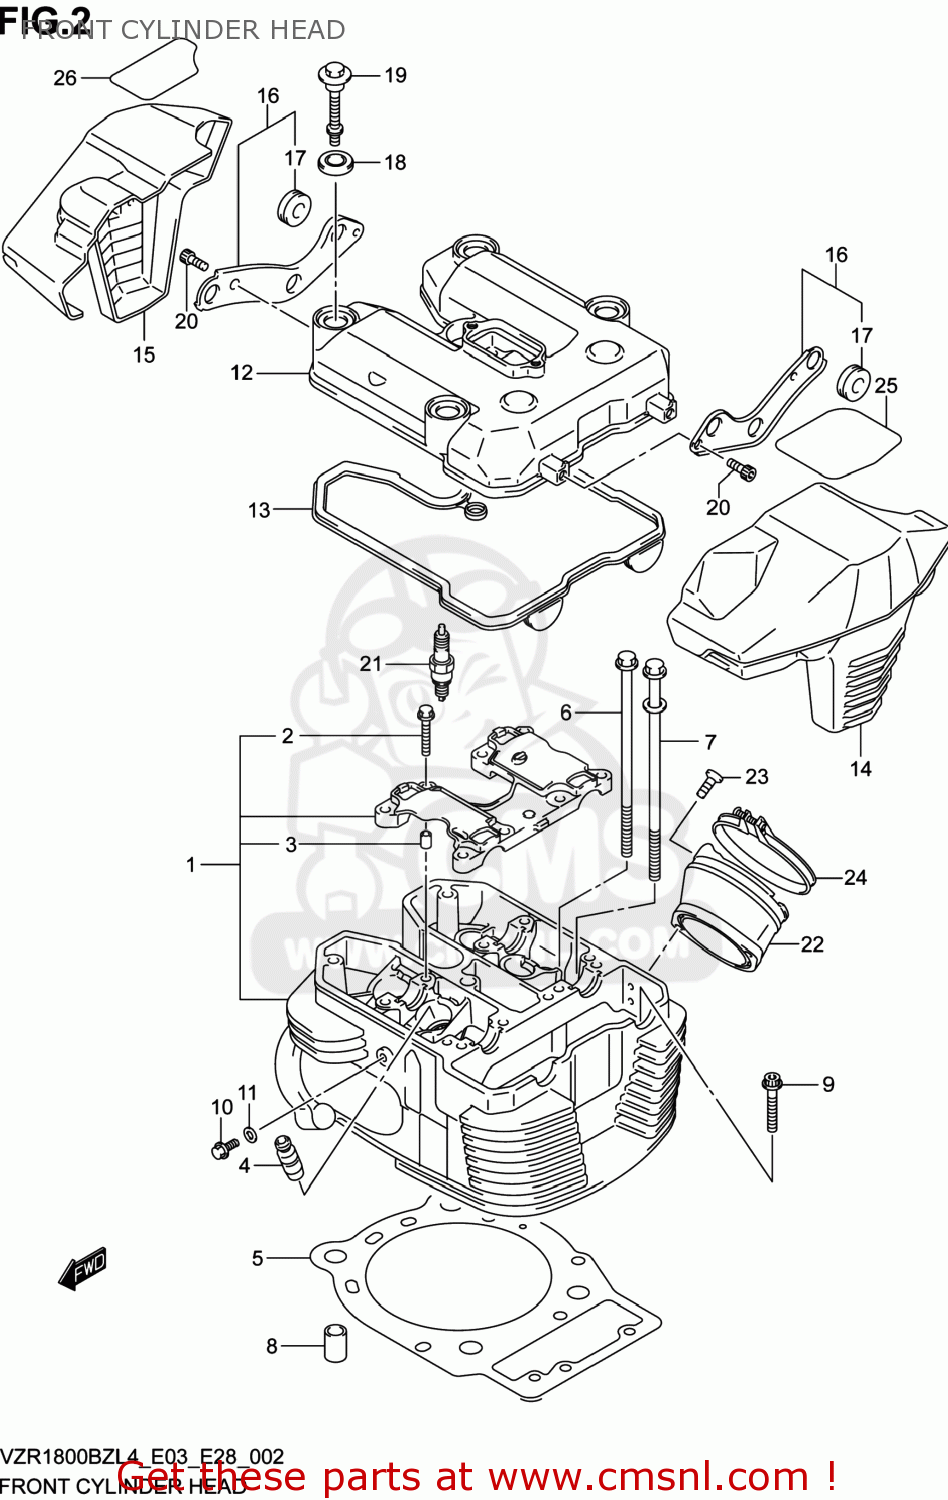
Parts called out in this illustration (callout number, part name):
1	HEAD ASSY,CYLINDER FR
2	BOLT(6X39)
3	PIN(6.2X8X11)
4	GUIDE,VALVE
5	GASKET,CYLINDER HEAD FR (NAS)
6	BOLT(8X180)
7	BOLT(10X19)
8	PIN
9	BOLT
10	BOLT(6X12)
11	GASKET(5.8X13X1.2) (NAS)
12	COVER,CYLINDER HEAD
13	GASKET,CYL HEAD COVER (NAS)
14	CAP,CYL HEAD COVER NO.1
15	CAP,CYL HEAD COVER NO.2
16	BRACKET,HEAD COVER CAP
17	CUSHION
18	CUSHION,HEAD COVER BOLT
19	BOLT(6X52)
20	BOLT
21	PLUG,SPARK(CR8EK)
22	PIPE ASSY,INTAKE
23	BOLT(6X20.5)
24	CLAMP,INTAKE PIPE
25	PROTECTOR,HEAD COVER CAP NO.1
26	PROTECTOR,HEAD COVER CAP NO.2
